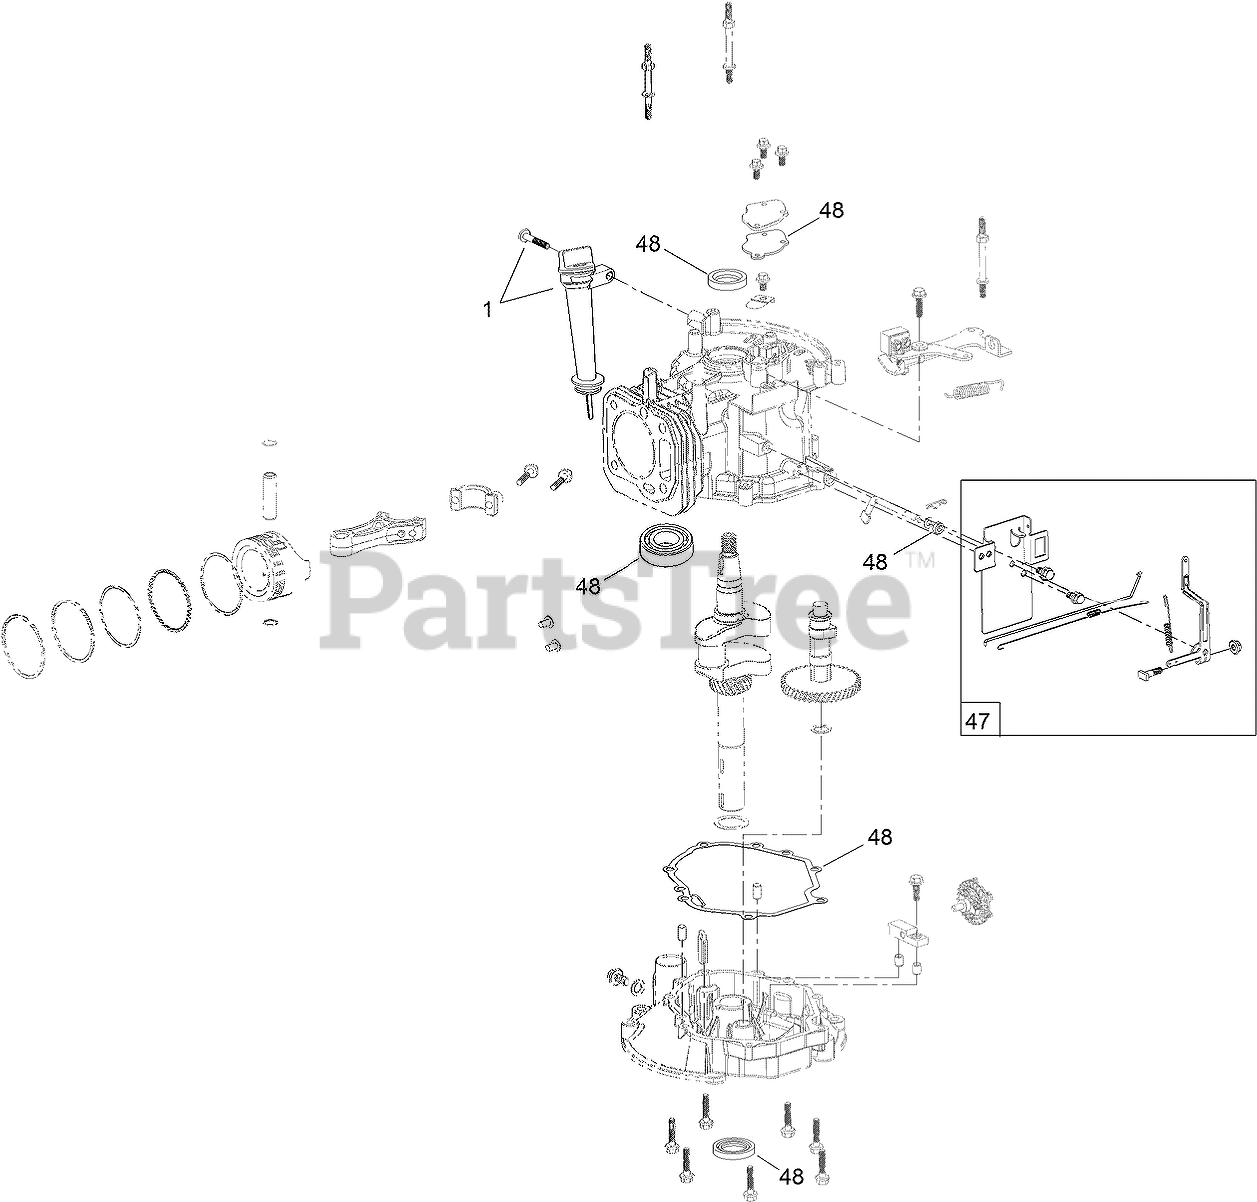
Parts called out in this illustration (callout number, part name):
1	DIPSTICK AND FILL TUBE KIT
47	GOVERNOR ARM KIT
48	SEAL AND GASKET KIT
